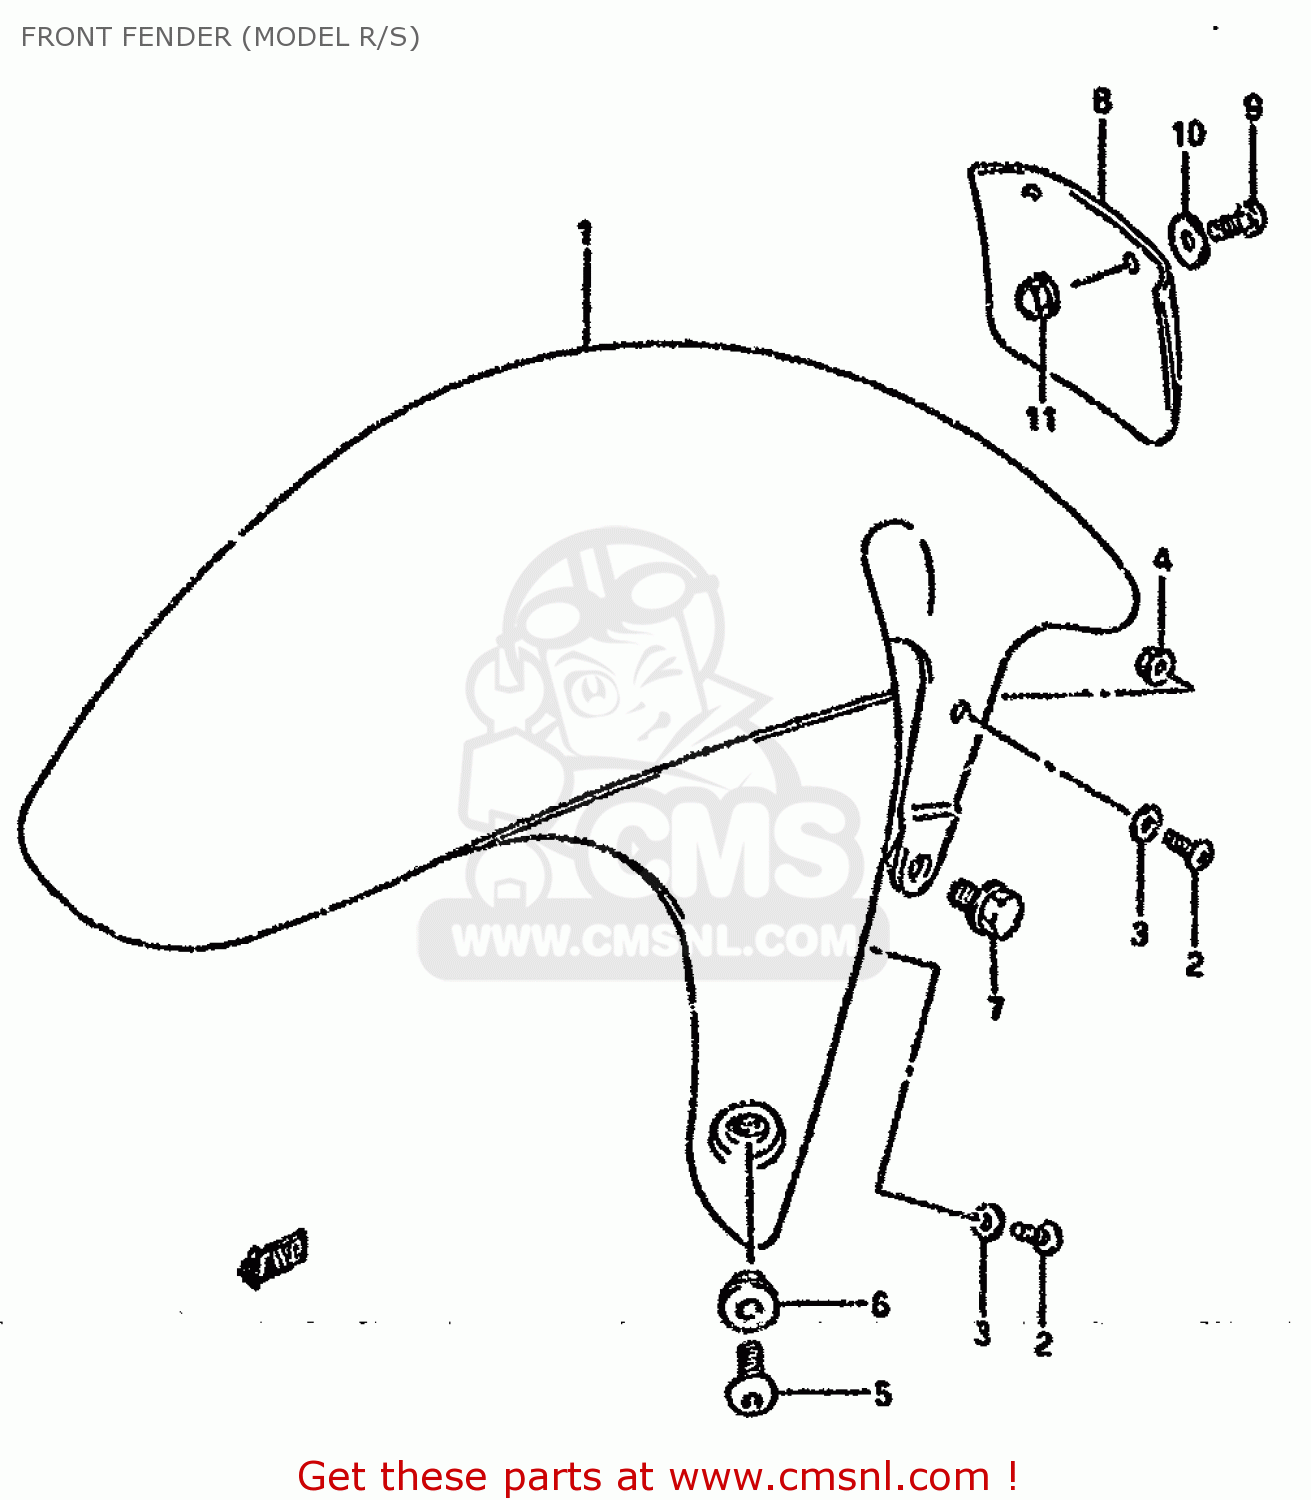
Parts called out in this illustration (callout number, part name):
1	FENDER,FR
2	SCREW
3	WASHER
4	NUT
5	SCREW(6X16)
6	WASHER(6.3X16X1.5)
7	BOLT
8	MUD GUARD,FR.F
9	SCREW 5X12
10	WASHER(5.5X20X1.2)
11	NUT
